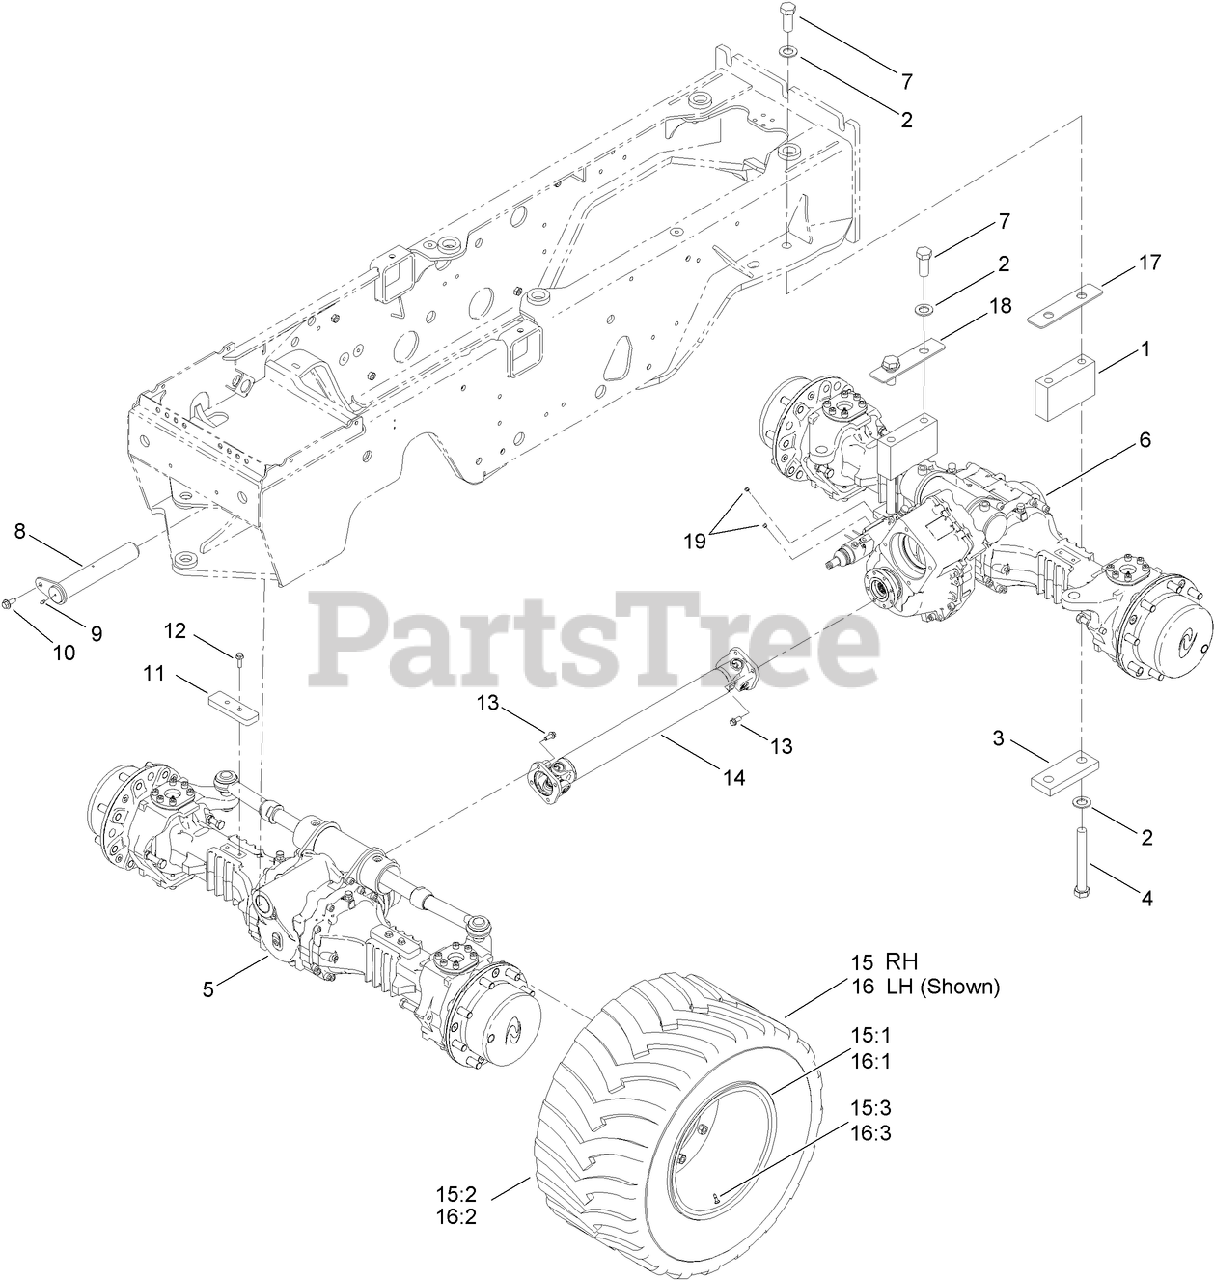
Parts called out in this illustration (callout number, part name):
1	SPACER-AXLE
3	BAR-CLAMP
4	SCREW-CAP
5	FRONT AXLE ASM
6	REAR AXLE ASM
9	FITTING-GREASE
10	SCREW-HHF
11	PLATE-STOP, PIVOT
12	SCREW-HHF
13	SCREW-HHF
14	FRONT AXLE DRIVE SHAFT ASM
15	RH WHEEL AND TIRE ASM
15:2	TIRE-31 INCH
15:3	STEM-VALVE
16	LH WHEEL AND TIRE ASM
16:2	TIRE-31 INCH
16:3	STEM-VALVE
17	PLATE-SPACER
18	PLATE-SPACER
19	PLUG-PIPE
